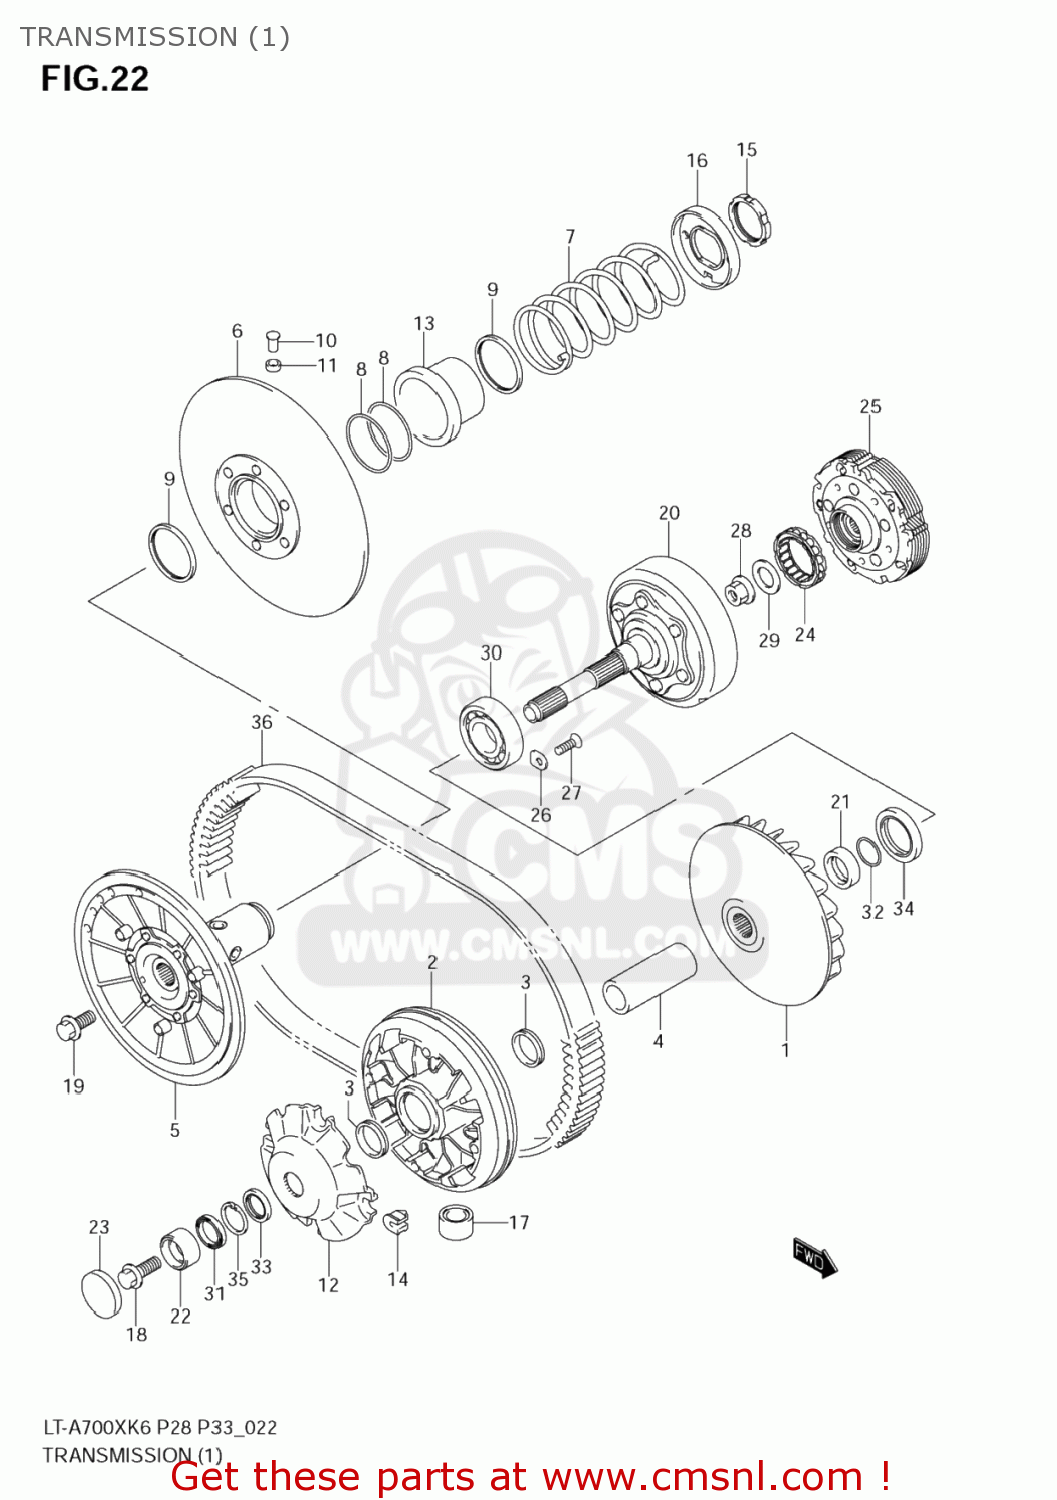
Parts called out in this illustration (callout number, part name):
1	FACE,FIXED DRIVE
2	FACE,MOVABLE DRIVE
3	SEAL,MOVABLE DRIVE FACE OIL
4	SPACER,MOVABLE DRIVE
5	FACE,FIXED DRI
6	FACE,MOVABLE D
7	SPRING,MOVABLE DRIVEN
8	O RING,MOVABLE DRIVEN
9	SEAL,MOVABLE DRIVEN
10	PIN,MOVABLE DRIVEN
11	SPACER,MOVABLE DRIVEN PIN
12	PLATE,MOVABLE DRIVE
13	SHEET,MOVABLE DRIVEN
14	DAMPER,MOVABLE DRIVE PLATE
15	NUT,DRIVEN PULLEY SPRING
16	HOLDER,MOVABLE DRIVEN SPRING
17	ROLLER,MOVABLE DRIVE
18	BOLT(12X30)
19	BOLT(12X25)
20	HOUSING,CLUTCH
21	SPACER,PRIMARY SHAFT
22	SPACER,CLUTCH HOUSING BRG
23	CAP,V-BELT BEARING HOUSING
24	CLUTCH,PRIMARY DRIVE ONE WAY
25	CLUTCH ASSY,SHOE (NAS)
26	RETAINER,COUNTER BEARING,R
27	SCREW(6X12)
28	NUT
29	WASHER
30	BEARING(28X68X18)
31	BEARING(35X47X7)
32	O RING(D:2.4,ID:24.7)
33	SEAL,OIL(35X47X5)
34	SEAL,OIL(38X56X7)
35	CIRCLIP
36	V-BELT,DRIVE
